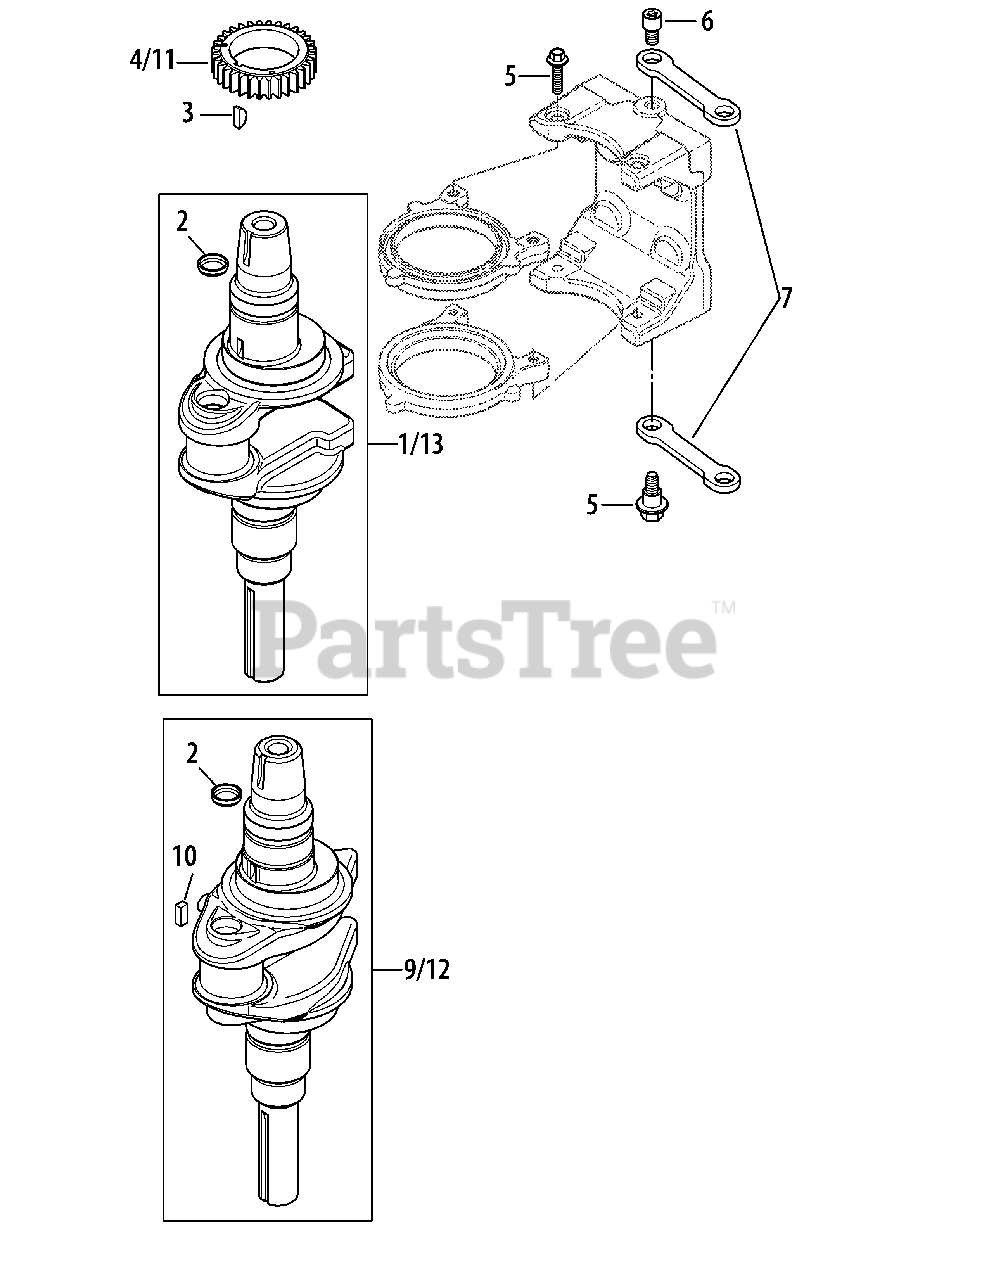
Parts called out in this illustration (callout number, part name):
1	Crankshaft Assembly Kit
3	Key, 3/16 X 5/8
4	Crankshaft Gear
5	Shoulder Screw
6	Link Pivot Screw
7	Balance Weight Linkage
